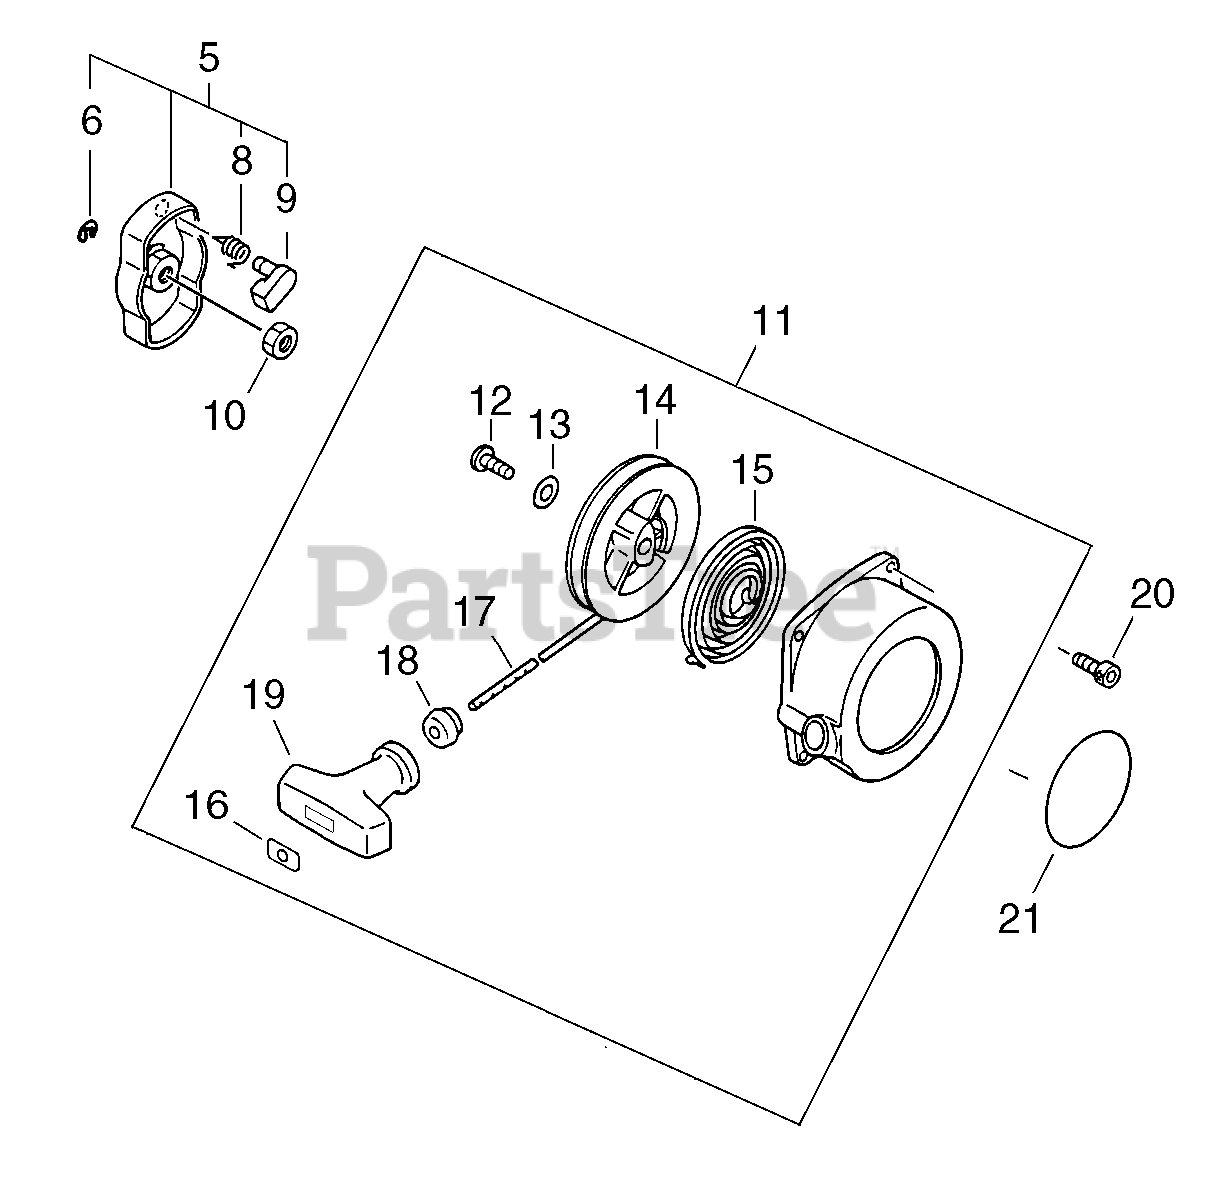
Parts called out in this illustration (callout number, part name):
5	STARTER PAWL ASSY
6	RING, RETAINING - 4
8	SPRING, RETURN
9	PAWL, STARTER
11	STARTER ASSY
14	REEL, ROPE
15	SPRING, REWIND
16	RETAINER, ROPE
17	ROPE, STARTER - 4X880
18	GUIDE, ROPE
19	GRIP, STARTER
20	SCREW - 4X20
21	LABEL - ECHO
